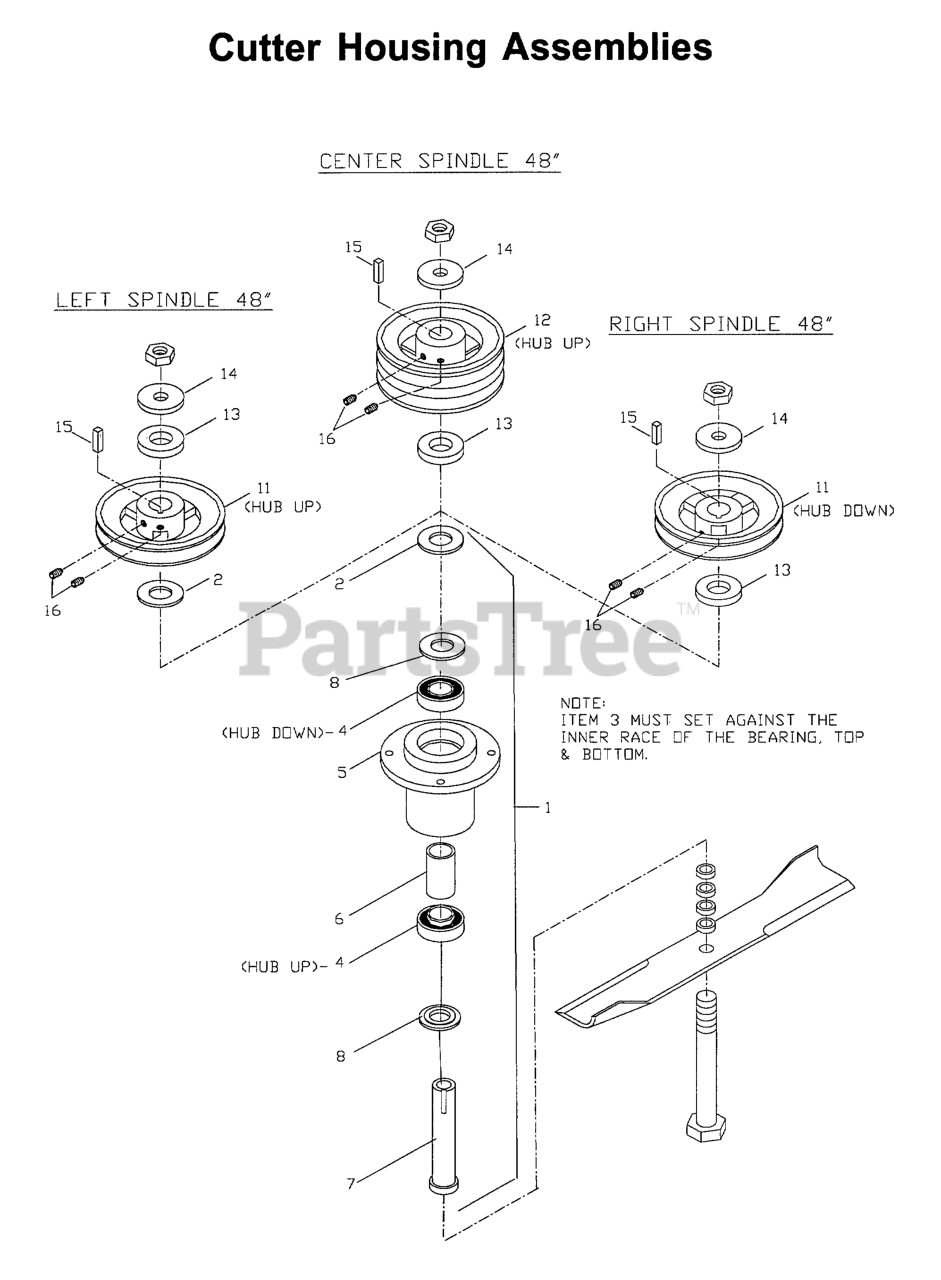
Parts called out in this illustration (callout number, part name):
1	HOUSING ASSEMBLY
2	MACHINERY BUSHING 10 GA.
4	BEARING
7	SPINDLE SHAFT
8	COMBO SPACER
11	PULLEY W/SETSCREWS
12	PULLEY, DOUBLE W/SETS
14	WASHER, SUPPORT
15	KEY 1/4 SQ X 1 1/8
16	SET SCREW 5/16 NYLOC
